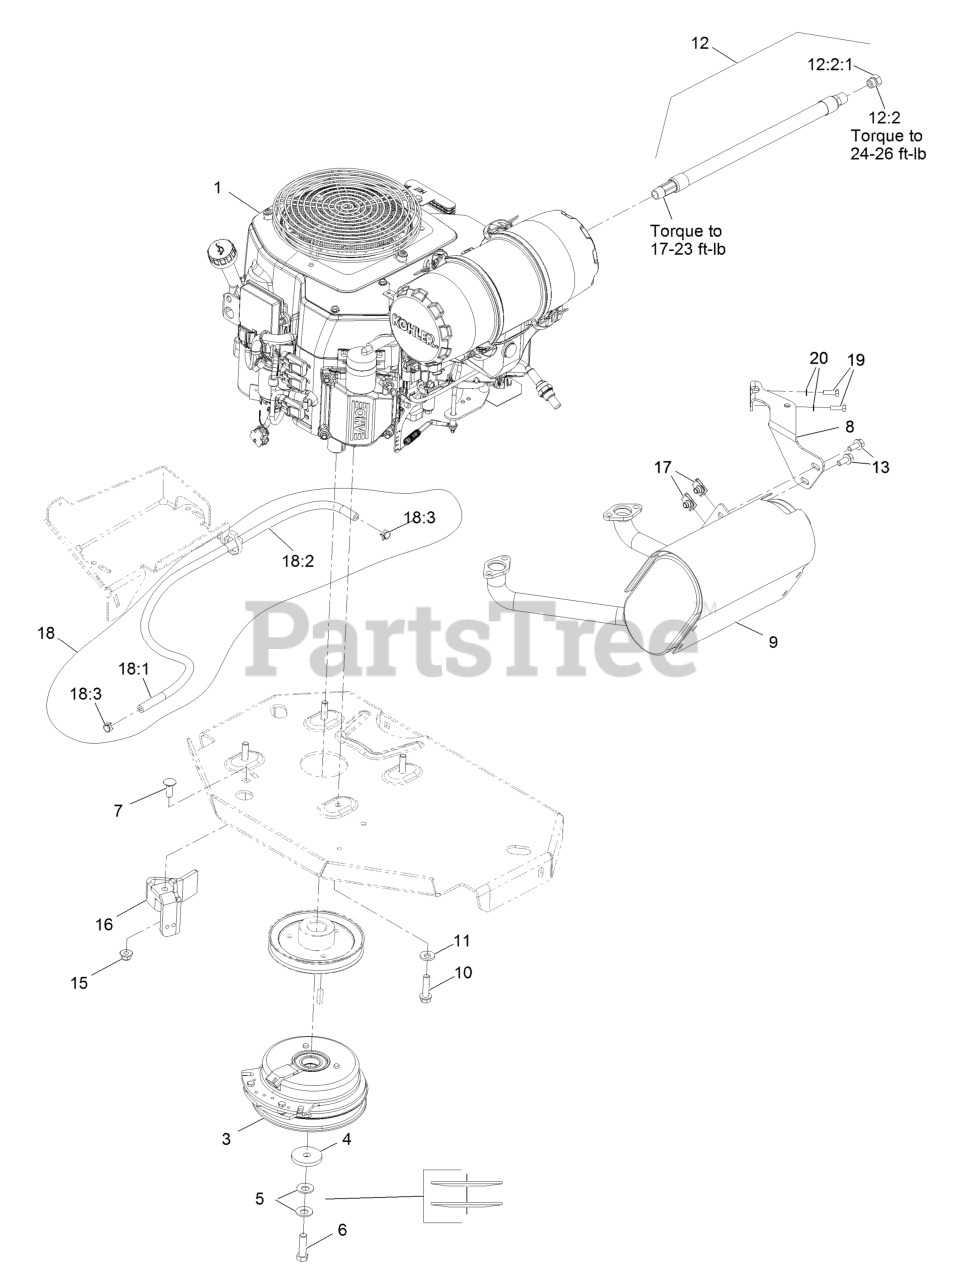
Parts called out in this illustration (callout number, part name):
3	CLUTCH KIT
4	WASHER-CLUTCH
5	WASHER-SPRING
6	SCREW-HH 7/16-20 X 1 1/2 W/LOCTITE
7	SCREW-CARR
8	MUFFLER BRACKET KIT
10	SCREW-HWH
11	WASHER-BELLEVILLE
12	OIL DRAIN HOSE ASM
12:2	PLUG-HH
12:2:1	O-RING
13	SCREW-HHF
15	NUT-HF, NI
16	CLUTCH-ANCHOR
18	FUEL LINE ASM
18:1	HOSE-FUEL
18:2	SLEEVE-THERMAL
18:3	CLAMP-HOSE
19	SCREW-HH M6-1 X 20Mm W/Patch
20	WASHER-SPRING
